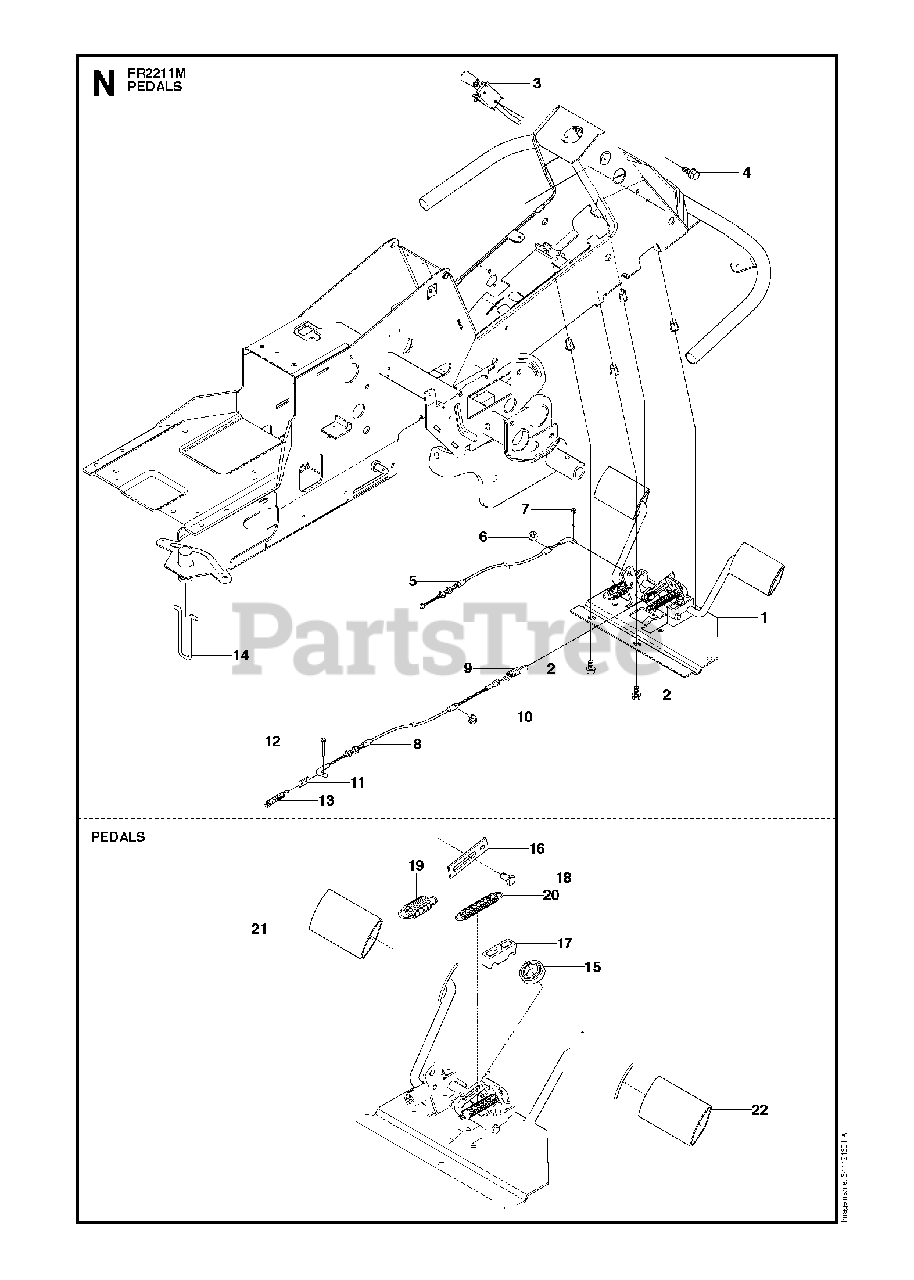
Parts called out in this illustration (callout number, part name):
3	BRAKE LEVER ASSY
7	COTTER PIN
11	CONNECTOR
12	COTTER PIN
15	BALL BEARING 6002-2RS1
17	PEDAL SHAFT CLAMP
18	CLEVIS PIN
21	PEDAL RUBBER, SF
22	PEDAL RUBBER, SF
